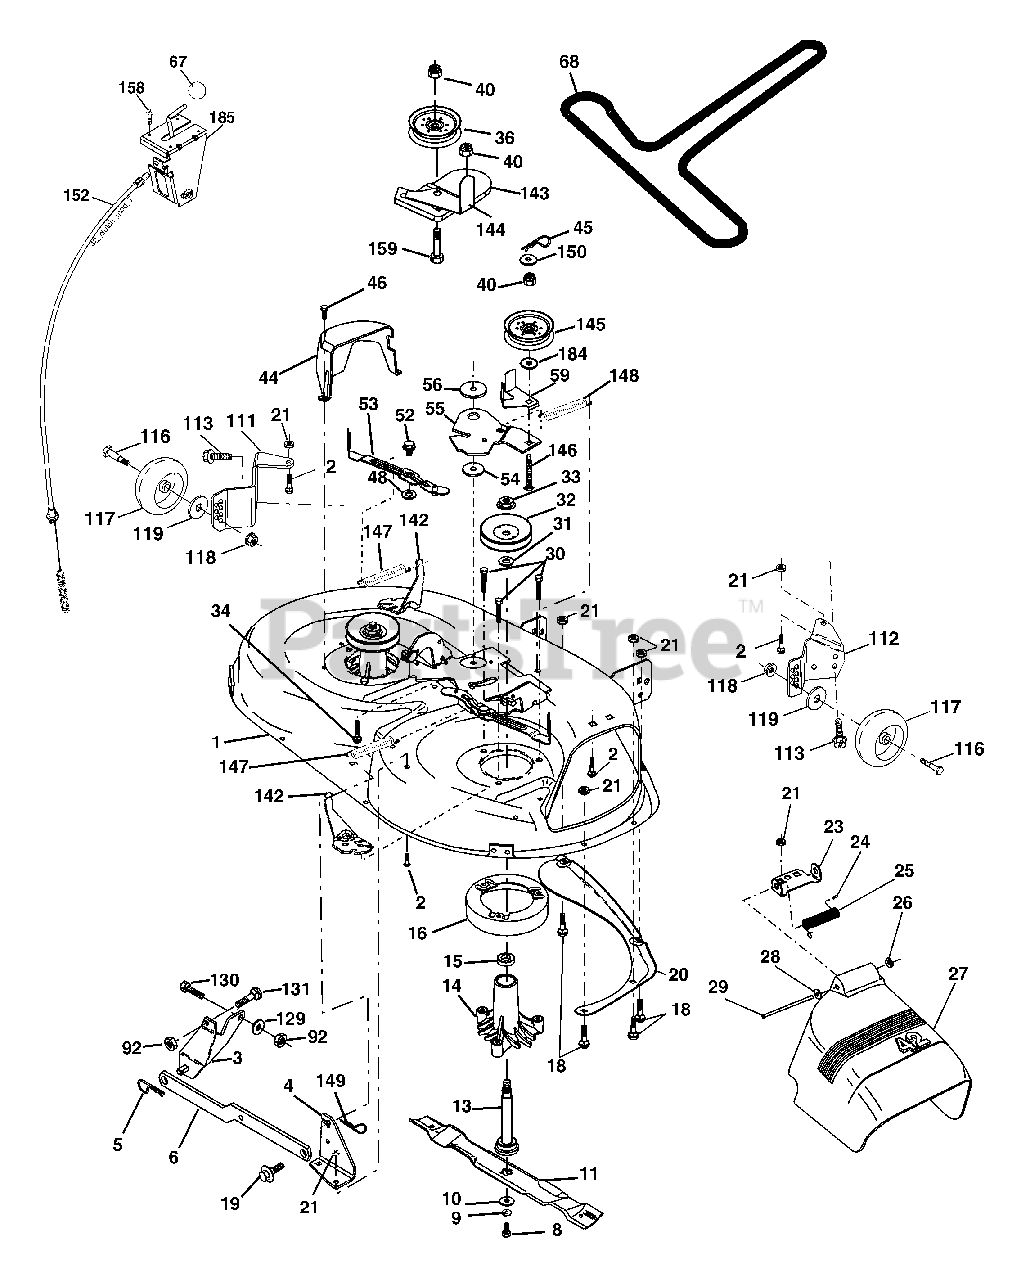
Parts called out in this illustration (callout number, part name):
1	Deck Asm MWR 42" weldment
2	Bolt Rdhd Sqnk 5/16-18 unc x 3/4
3	Bracket Asm Fr Sway Bar 38/42
4	Bracket Asm Deck 42" sway Bar
5	Retainer Spring
6	Deck Sway Bar
8	Bolt 3/8 - 24 x 1.25 Gr. 8
9	Washer Lock Hvy 3/8
10	Washer Hard Blade Mower Vented
11	Blade Mower 42"
11	Blade, 42" Mulching Premium
11	Blade, 42" Hi-Lift
13	Shaft Asm W/lower Bearing
14	Housing Mandrel Vented
15	Bearing Ball Mandrel
16	Stripper Mower
18	Bolt Rdhd Sqnk 5/16-18 x 5/8
19	Bolt Shoulder
20	Baffle Vortex 42
21	Nut Crownlock 5/16-18 unc
23	Bracket Deflector Mower 42"
24	Cap Sleeve 80 x 112 Blk Mower
25	Spring Torsion Deflector 2 52
26	Nut Push Phos & Oil
27	Shield Deflector Mower 42" Blk
28	Washer 11/32 x 5/8 x 16 Ga.
29	Rod Hinge 42" 6 75 Wlg
30	Screw Thd Rolling
31	Washer Spacer
32	Pulley Mandrel 42"
33	Nut Toplock Flng
34	Bolt Rdhd 3/8-16 unc x 1-1/2 Gr. 5
36	Pulley Idler Flat
37	Washer 13/32 x 13/16 x 16
40	Nut Lock 3/8-16 unc
44	Guard Mandrel LH Black
45	Spring Retainer 1" Zinc/cad
46	Screw Hex Thd Cut 1/4-20 x 5/8 T
48	Washer Hardened Smaller
52	Bolt Shoulder 5/16-18 unc Blkz
53	Arm Asm Pad Brake
54	Washer Hardened
55	Arm Idler 42" mower LT/YT
56	Spacer Retainer Mower
59	Guard TUV Idler
67	Knob Rd 3/8-16 Plstc Thds Blk
68	V-Belt Mower 42"
92	Nut 3/8-16 unc
111	Bracket Wheel Gauge LH
112	Bracket Wheel Gauge RH
113	Bolt 5/16-18 Hex Whs-Hd Lck Ser.
116	Bolt Shoulder
117	Wheel Gauge
118	Nut Lock 3/8-16 unc
119	Washer 3/8 x 7/8 x 14 Ga.
129	Washer 13/32 x 13/16 x 12 Ga.
130	Bolt 3/8-16 x 1 Gr. 5
131	Bolt 3/8-16 x 1
142	Arm Spring Brake Mower
143	Bracket Arm Idler 42"
144	Keeper Belt 42" Clutch
145	Pulley Idler Flat
146	Bolt Carriage Idler
147	Spring Extension
148	Spring Return Idler
149	Retainer Spring Yellow
150	Washer 9/32 x 3/4 x 16 Ga.
152	Clutch Cable 42"
158	Screw Hex Thd Cut 1/4-20 x 1/2
159	Bolt Rdhd Sqn 3/8-16 unc x 1-3/4
184	Washer 13/32 x 7/8 x 10 Ga.
185	Head Asm. Cable Clutch
